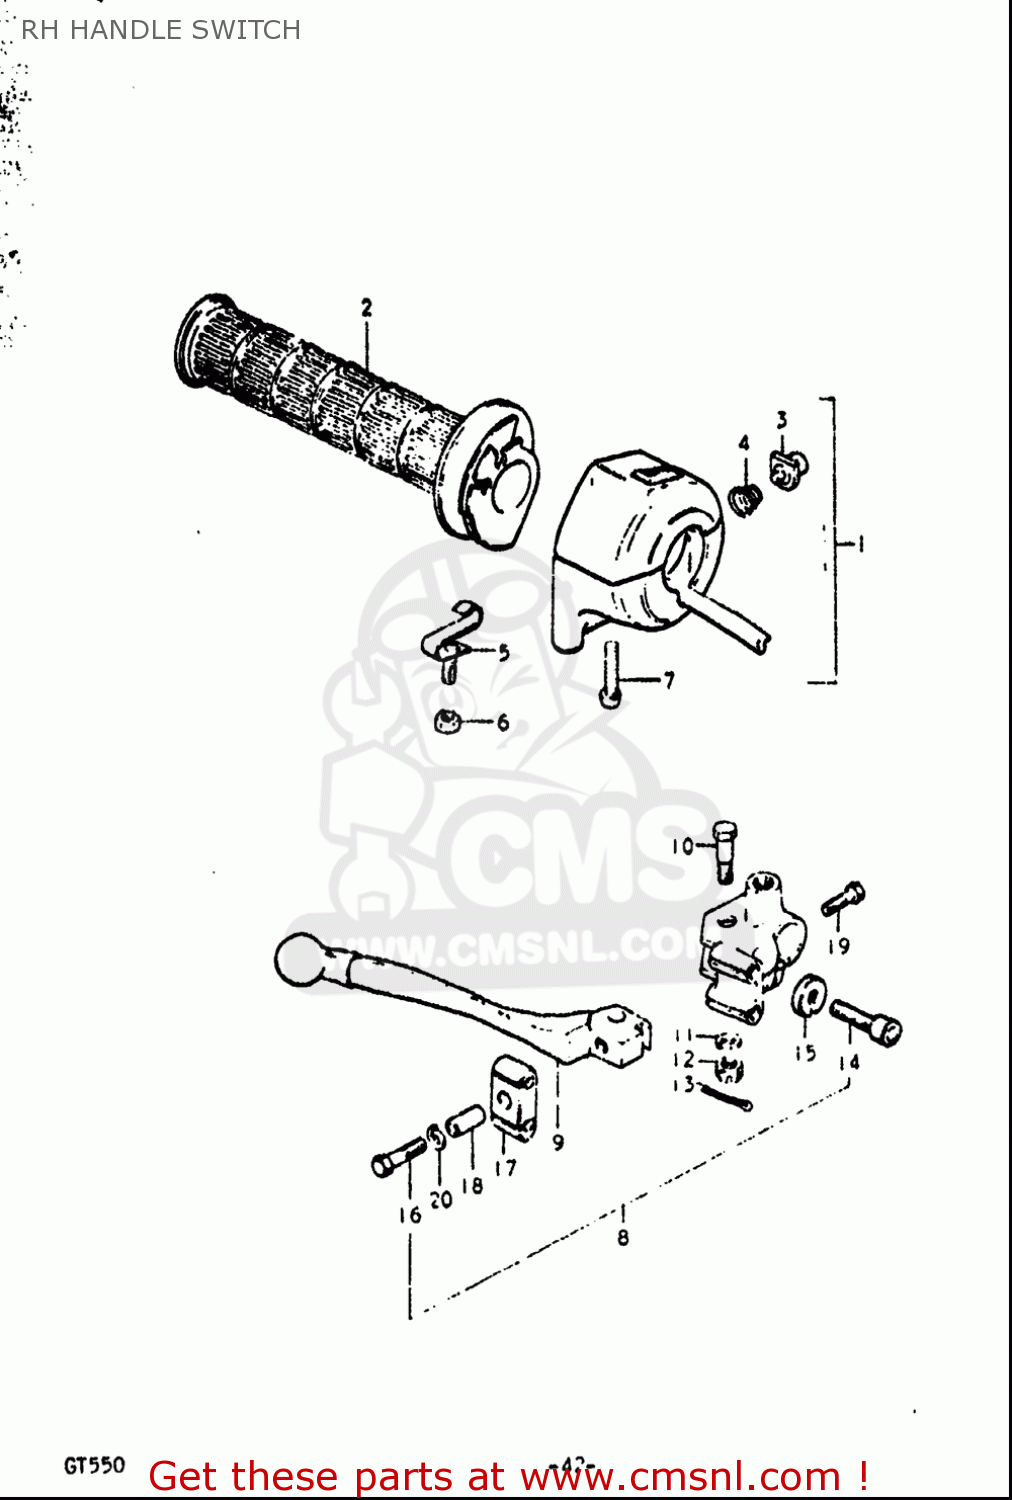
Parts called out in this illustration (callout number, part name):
2	GRIP,THROTTLE
3	BUTTON
4	SPRING
5	ADJUSTER, THROTTLE
6	NUT
7	SCREW
8	SWITCH ASSY,HANDLE,R
10	BOLT,LEVER PIVOT
11	WASHER,LOCK
12	NUT,LEVER FITTNG
13	PIN 16X20
14	ADJUSTER,CABLE
15	NUT,CABLE ADJUSTER
16	BOLT
20	WASHER,LOCK
